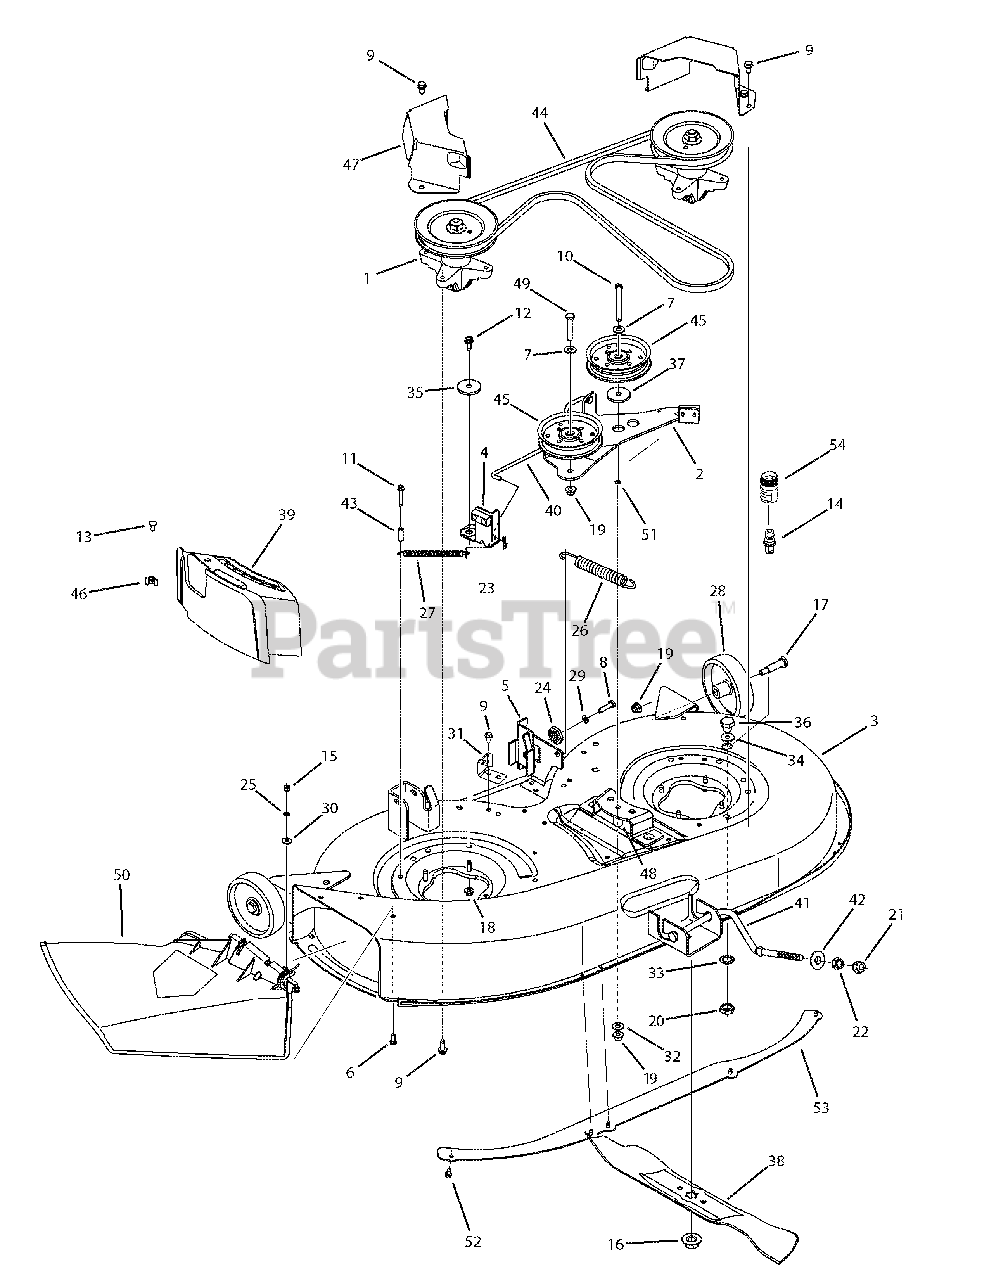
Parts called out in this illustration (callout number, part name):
1	Spindle Assembly, Pul, 6.3" Dia
3	Deck Shell, 42" (w/o Wheel Brkt)
6	Screw, 1/4-20, .75, Gr5
7	Washer, Flat, .385 x .75 x .062
8	Screw, 5/16-18, 1.250
9	Screw, 5/16-18, 0.750
10	Screw, 3/8-16, 3.50, Gr5
11	Screw, 1/4-20, 1.500
12	Screw, 5/16-18, .75, Gr5
13	Carriage Screw, , 1/4-20 x .62
14	Deck Water Nozzle
15	Nut, Hex, 1/4-20, Gr5
16	Nut, Flange, 5/8-18
17	Screw, Shldr, .498 x 1.53, 3/8-16
18	Nut, Flange Lock, 5/16-18, GrF
19	Nut, Flange Lock, 3/8-16, GrF
20	Nut, Hex, M16-1.5
21	Nut, Hex Lock, 1/2-13, Gr8
22	Nut, Hex, 1/2-13, Gr5
23	Pin, Cot, .072 Dia. x 1.13 Lg
24	Gear, Deck Adjustment
25	Nut, Push, .25 ID x .50 OD
26	Spring, Exten., .75 Dia. x 6.375
27	Spring, Exten., .50 Dia. x 6.375
28	Wheel, Deck 5.0 x 1.38
29	Washer, Lock, 5/16
30	Washer, Bell, .265 x.75 x .062
32	Washer, Flat, .406 x .875 x .059
33	Washer, Lock, 5/8, Internal Tooth
34	Washer, Flat, .64 x 1.24 x .06
35	Spacer, Shoulder, .5000 x .1475
36	Plug, Screw, M16 x 1.5
37	Spacer, Shoulder, .8840 x .190
38	Blade, 21.23", Star 3-in-1
39	Mulch Plug
40	Control Rod, Brake
41	Deck Rod, Front Adjustable
42	Pivot Cup, Deck Lift
43	Spacer, .260 x .372 x 1.030
44	Belt, V-Type
45	Idler Pulley, 4.25" Dia.
46	Wing Nut, 1/4-20
48	Spacr, 3/8 ID x .68 OD x 1.46 Lg.
49	Screw, 3/8-16 x 1.75
50	Chute Assembly, Discharge
51	Nut, Push, 3/8
52	Screw, 1/4-20, 0.500
54	Water Nozzle Adapt
